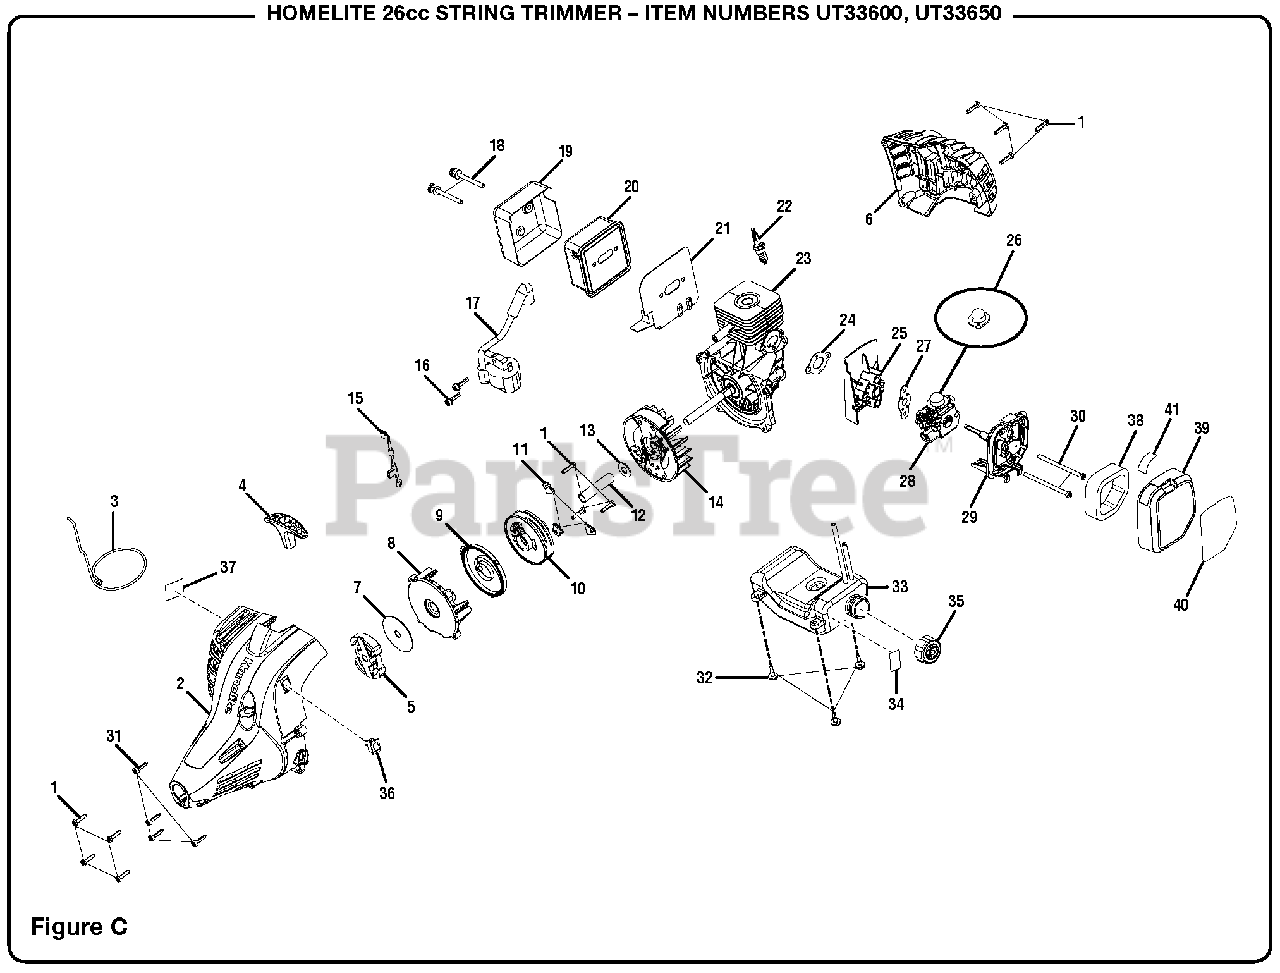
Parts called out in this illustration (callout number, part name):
1	Screw (M4 x 18 mm, T20 Torx Pan Hd.)
2	Starter Housing Assembly
3	Starter Rope (42 in.)
4	Pulley Handle
5	Clutch Assembly
6	Rear Housing
7	Clutch Washer
8	Starter Housing
9	Spring & Container Assembly
10	Starter Pulley Assembly
11	Pulley Retainer
13	Washer
14	Flywheel Assembly
15	Lead Assembly
16	Screw w/Washer (M4 x 19 mm, T20 Torx Pan Hd.)
17	Ignition Module
18	Screw w/Washers (10-24 x 2-1/8 in., T25 Torx Truss Hd.)
19	Heat Shield
20	Muffler Assembly
21	Muffler Gasket
22	Spark Plug (RCJ6Y)
23	Short Block Assembly
24	Intake Gasket
25	Heat Dam Deflector
27	Carburetor Gasket
28	Carburetor Assembly
29	Air Box Base
30	Screw (M5 x 76 mm, T20 Torx Truss Hd.)
31	Screw w/Washer (M4 x 16 mm, T25 Torx Truss Hd.)
32	Shoulder Screw w/Washer (M4 x 14 mm, T25 Torx Truss Hd.)
33	Fuel Tank w/Label & Cap Assembly
34	Gas Tank Warning Label
36	Momentary Stop Switch
37	Combustion Warning Label
38	Air Filter
39	Air Box Cover
40	Starting Label
41	Choke Label
